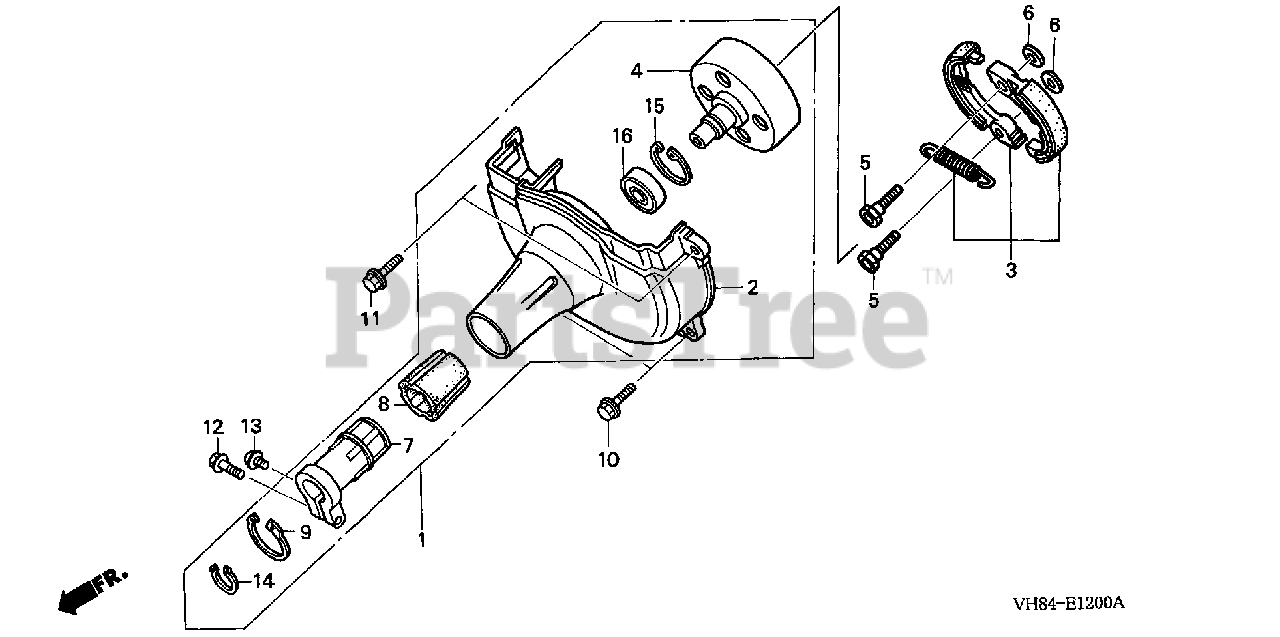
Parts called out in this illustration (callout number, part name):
1	COVER ASSY., FAN *NH35M* (CLOUD SILVER METALLIC)
2	COVER, FAN *NH35M* (CLOUD SILVER METALLIC)
3	CLUTCH ASSY.
4	CLUTCH (OUTER)
5	BOLT, CLUTCH (8MM)
6	WASHER, CLUTCH (8X17)
7	BRACKET, ENGINE MOUNTING
8	RUBBER, ENGINE MOUNTING
9	CIRCLIP (INNER) (45MM)
10	BOLT, FLANGE (5X18)
11	BOLT, FLANGE (5X22)
12	BOLT-WASHER (6X28)
13	SCREW-WASHER (5X10)
14	CIRCLIP, OUTER (15MM)
15	CIRCLIP (INNER) (35MM)
16	BEARING, RADIAL BALL (6202)
